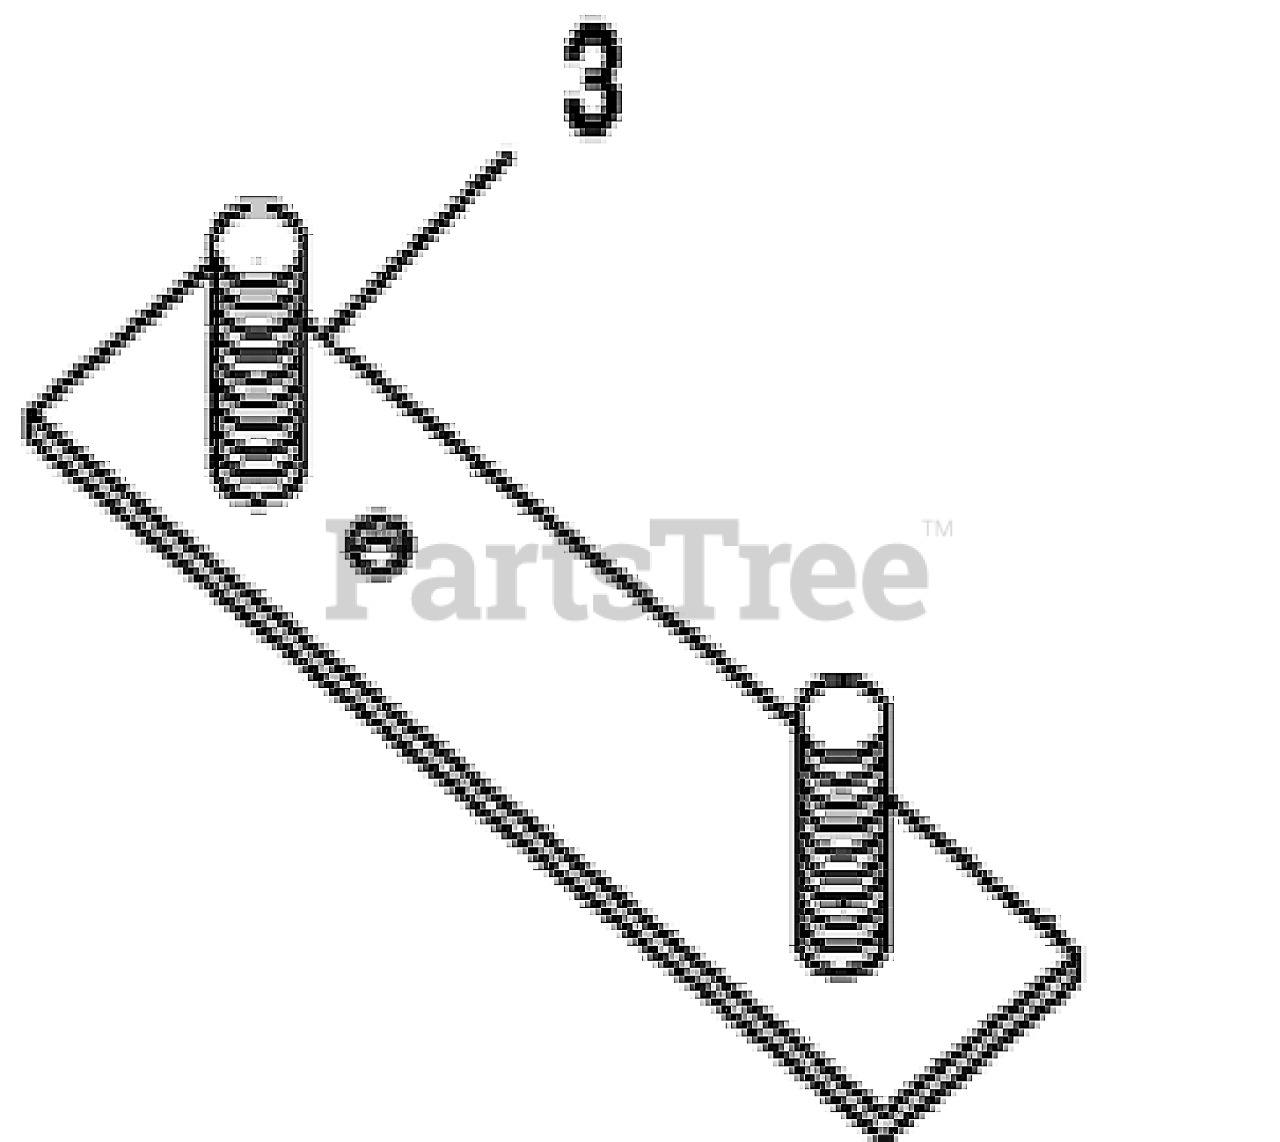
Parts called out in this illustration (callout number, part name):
1	SEAT.TH150.MS498.GRY.HUSQ.TEX
2	BRKT.PIVOT.FENDER
3	STRAP
6	NUT
7	SPRING.COMPRESS.SEAT.TAPERED
8	BOLT.5/16-18UNCX3/4 W/SEMS.BLK
10	PLATE.PNT.SEAT.SLIDE.3PT.EDIP
21	BOLT.5/16-18X5/8.SHOULDER
37	NUT.71038.31-18.HEX.NYLOCK
40	HANDLE.SLIDE.SEAT.TEX.BLACK
41	SPRING.LATCH.SEAT.TEX
44	WASHER.WINGED.3/8ID.1.5OD
46	BOLT.3/8-16X1;1.25OD.WSHR.SEMS
